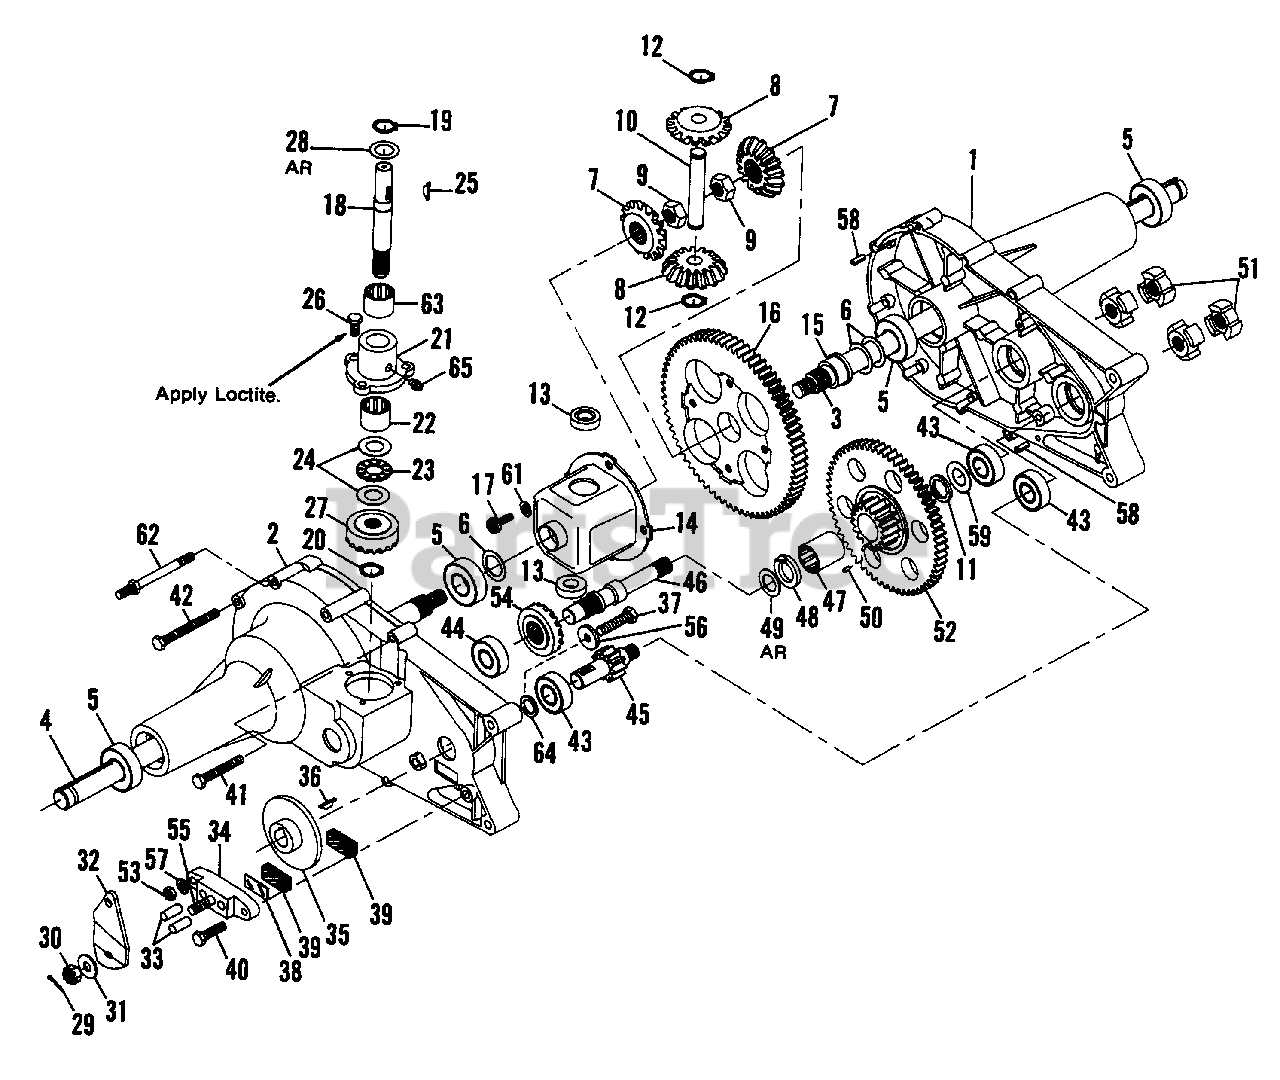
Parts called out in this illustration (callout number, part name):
1	HOUSING, Half, L.H.
2	HOUSING, Half, R.H.
3	AXLE, L.H., 3/4"
4	AXLE, R.H., 3/4"
5	BEARING, Ball
6	WASHER, Flat, 3/4 I.D. x 1-1/8 O.D. x .030 Thk.
7	GEAR, Miter
8	GEAR, Miter
9	NUT, Hex, Jam w/Patch, 1/2-20
10	SHAFT, Cross
11	GREASE, Seal, Bronze
13	BEARING, Thrust
14	HOUSING ASSY., Differential
15	BEARING, Flange
16	GEAR, Differential, Tooth
17	BOLT, Torx Hd., 1/4-29 x 5/8" Lg.
18	SHAFT, Input
20	RETAINING RING, 7/16" Dia. Ext.
21	HOUSING, Input Bearing
22	BEARING, Needle
23	BEARING, Thrust
24	WASHER, Flat, 5/8 I.D. x 1-1/8 O.D. x .030 Thk.
25	KEY, Hi-Pro, 1/8 x 5/8
26	SCREW, Hex, Socket Hd., 1/4-20 x 3/4 Long
27	GEAR, Input Pinion, 17 Tooth
28	WASHER, Flat, .62 I.D. x 1.0 O.D. x .030 Thk.
28	WASHER, Flat, .62 I.D. x 1.125 O.D. x .060 Thk.
29	PIN, Cotter
30	NUT, Castle, 5/16-24
31	WASHER, Flat, .343 I.D. x .88 O.D. x .062 Thk.
32	ARM, Brake Actuator
33	PIN, Brake Actuating
34	BRAKE, Yoke
35	DISC, Brake
36	KEY, Hi-Pro, 3/16 x 5/8" Dia.
37	SCREW, Hex, 1/4-20 x 1-1/2
38	PLATE, Puck
39	PUCKE Brake
40	SCREW, Hex w/Patch, 1/4-20 x 1.00 Lg.
41	SCREW, Hex, Self-Tap, 1/4-20 x 2.00 Lg.
42	SCREW, Hex, Self-Tap, 1/4-20 x 3.00 Lg.
43	BEARING, Ball
44	BEARING, Ball
45	SHAFT, Pinion w/11 Tooth Gear
46	SHAFT, Drive
47	BEARING, Needle
48	BRONZE THRUST BRG., 5/8 I.D. x 1-1/4 O.D. x 7/64 Thk.
49	WASHER, Flat, .62 I.D. x 1.0 O.D. x .050 Thk.
50	PIN, Dowel, 3/32 x 1/4
52	GEAR, 60 and 17 Tooth
53	NUT, Hex, 1/4-20
54	GEAR, Drive Pinion, 17 T.
55	BOLT, Square Head
56	WASHER, 1/4" Spring
57	WASHER, 1/4" spring Lock
58	PIN, Roll, 3/16" Dia. x 1/2" Lg.
59	WASHER, Flat, .621.D. x 1.0 O.D. x .030 Thk.
60	SHELL DURINA-O GREASE (20 Oz. Tube)
61	WASHER, Hd. Sprg. Lock,1/4" (Yellow Di-Chrom)
63	BEARING, Needle (w/Seal)
64	SEAL, Grease
65	GREASE FITTING
